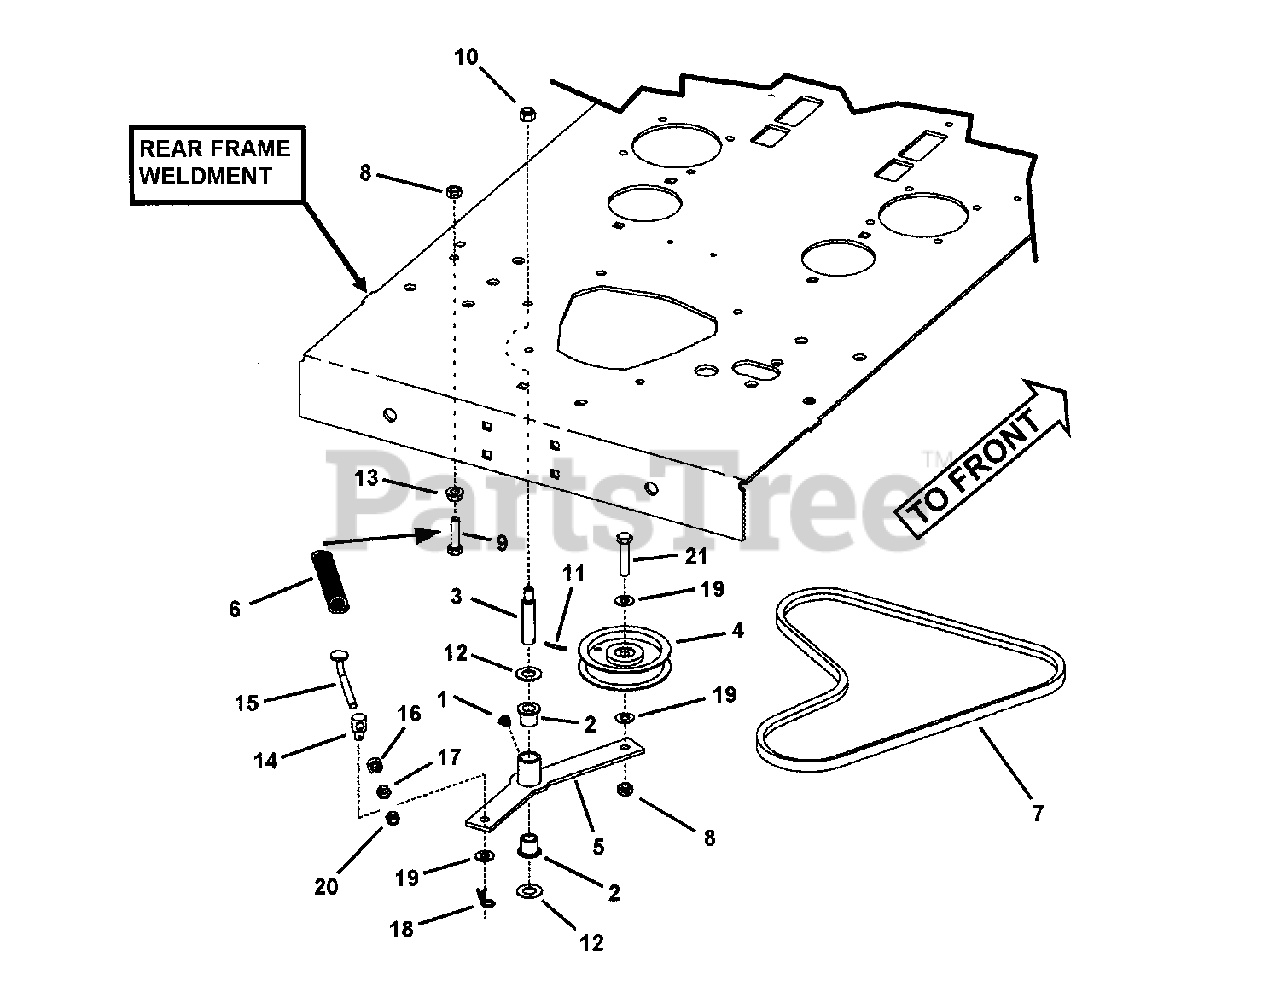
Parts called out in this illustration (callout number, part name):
1	FITTING, 3/16" Straight Lube
2	BUSHING, 9/16" I.D.
3	PIN, Idler Arm (3/8-24 Thread)
4	PULLEY, Flat Idler 4.12" (Backside Idler)
5	WELDMENT, Idler Arm
6	SPRING, Extension
7	BELT, Hydro Drive (HA Section, 47.5 Effective Length)
8	NUT, 3/8-16 Hex Center Lock
9	SCREW, 3/8-16 x 1-1/2 Hex Head Cap GR5
10	NUT, 3/8-24 Hex Nyloc
11	PIN, 1/8 x 3/4" Cotter
12	WASHER, 9/16" Flat
13	NUT, 3/8-16 HEX SERRATED FLANGE
14	SWIVEL, Adjustable
15	ADJUSTER, Chain (5/16-18 Thread)
16	SPACER, .340 I.D. x .63 O.D. x .310 Thick
17	NUT, 5/16-18 Hex, GR5 or B
18	HAIR PIN, 3/32 x 1-1/2"
19	WASHER, 3/8" Flat SAE
20	NUT, 5/16-18 HEX NYLON LOCK
21	SCREW, 3/8-16 x 1-3/4" Hex Head Cap GR5
